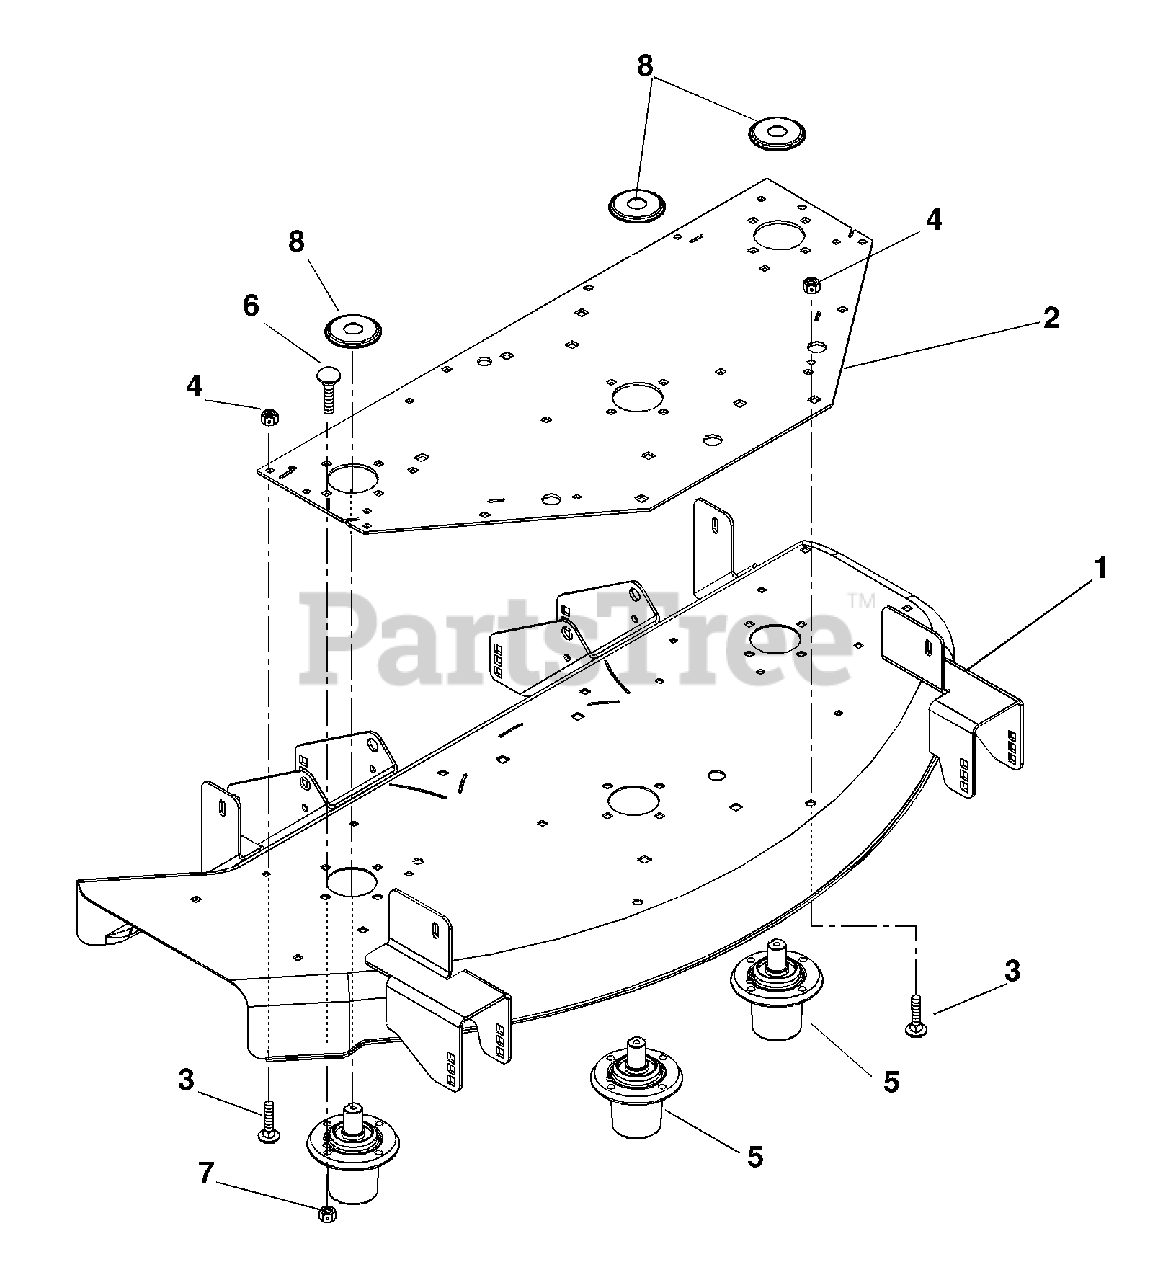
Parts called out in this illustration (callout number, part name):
1	Weldment, 50" Deck
2	Plate,Support 50"
3	Bolt-Round Head Square Neck .31-18 x .75 Grade 5
4	Nut-Locking-Nylon .312-18
5	Assembly, Spindle
6	Bolt-Round Head Square Neck .38-16 x 1.50 Grade 5
7	Nut-Locking-Nylon .38-16
8	Slinger, Dust
